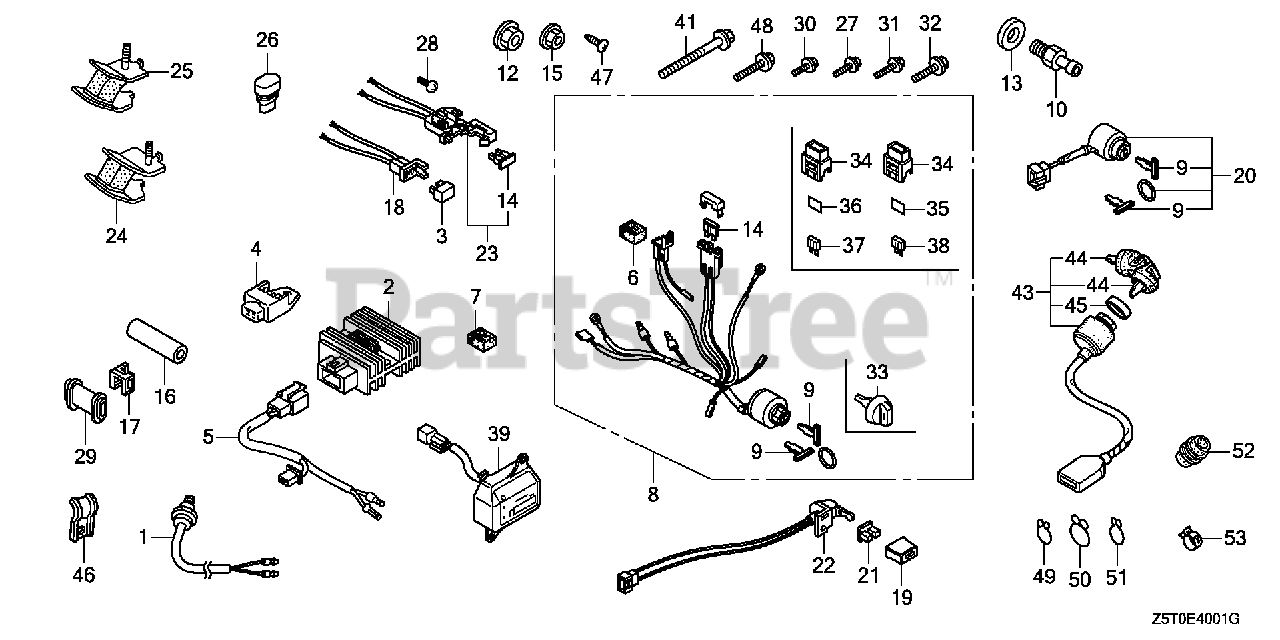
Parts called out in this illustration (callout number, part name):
6	SUSPENSION, CONNECTOR
8	SWITCH ASSY., COMBINATION (3A-CHARGE)
9	KEY
12	NUT, FLANGE (8MM)
14	FUSE, BLADE (5A)
27	BOLT, FLANGE (6X12) Use up to Engine SN 1543277.
